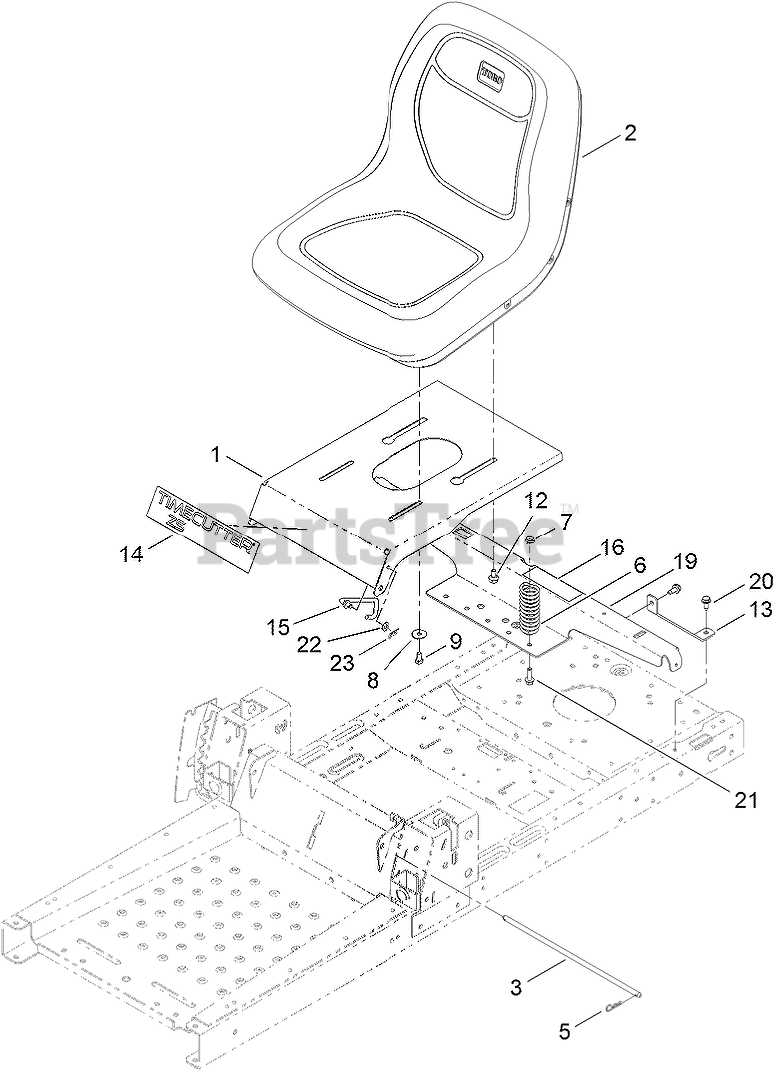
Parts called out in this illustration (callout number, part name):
1	PAN-SEAT
2	SEAT-18 INCH
3	ROD-PIVOT, NARROW
5	PIN-COTTER
6	SPRING-COMPRESSION
7	NUT-HF, NI
8	WASHER-PIVOT
9	SCREW-HH
12	BOLT-SHOULDER
13	SUPPORT-TANK, REAR
14	DECAL-TIMECUTTER
15	STOP-SEAT
16	DECAL-SERVICE, CE
19	SUPPORT-POD
20	SCREW-HWHTF
21	SCREW-HHF
22	WASHER-PLAIN
23	PIN-COTTER
